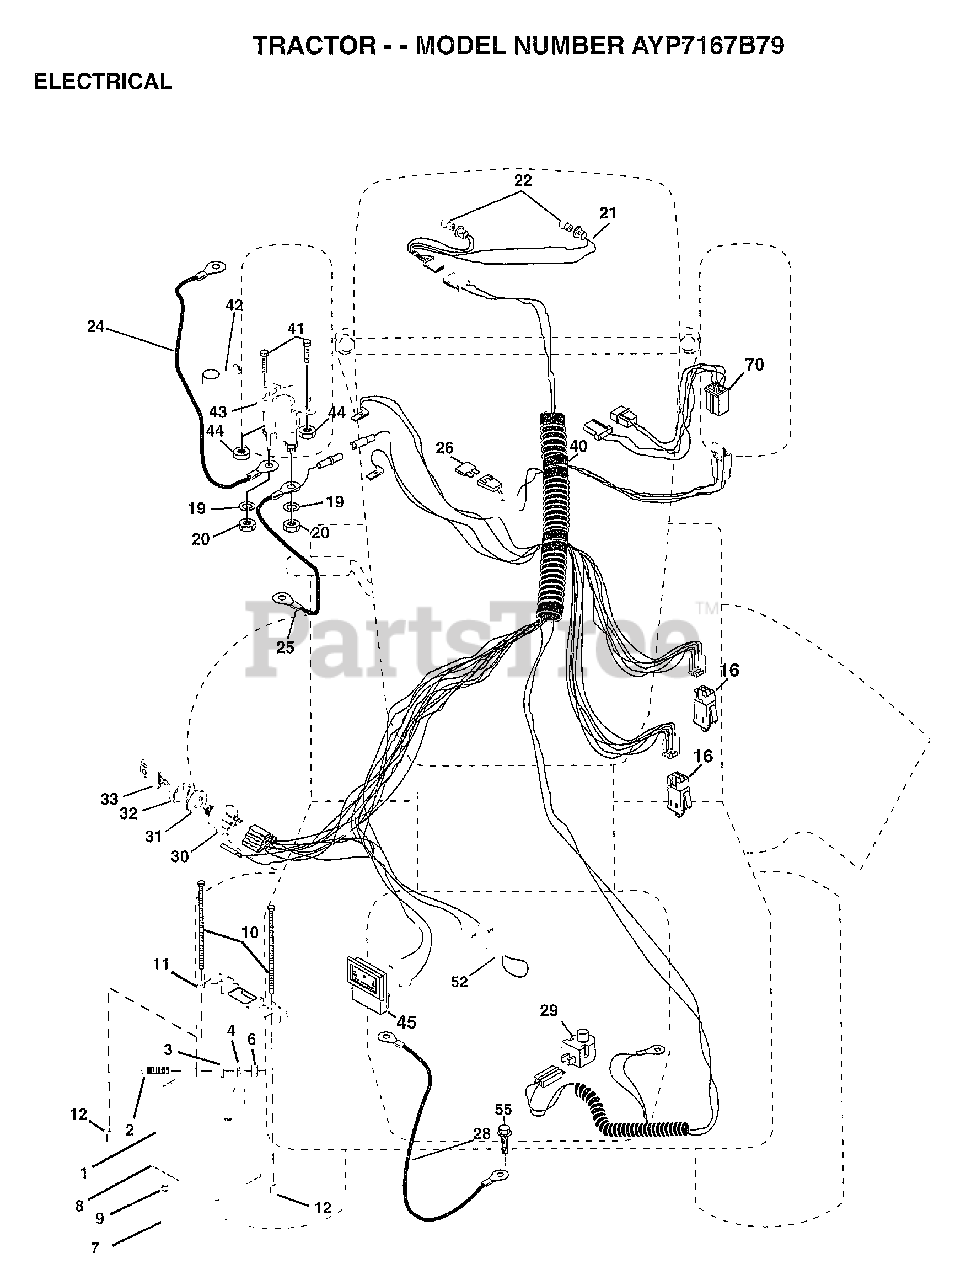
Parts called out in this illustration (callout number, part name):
2	BOLT LT
3	WASHER
4	LOCKWASHER
7	"DRAIN TU T, BATT"
8	"TRAY T, BATTERY"
9	HOSE CLAMP T
11	HOLDDOWN BATTERY
16	SWITCH INTERLOCK
20	NUT
21	"HARNESS,LIGHT SOC"
22	HEADLAMP BULB
24	"CABLE T, BATTERY"
25	CABLE.6GA.22W/16W
26	FUSE HYT
28	CABLE.GRND.6GA.21
29	SWITCH SEAT
30	SWITCH IGN 4POS
31	NUT IGNITION
32	COVER KEY SWITCH
33	KEY
40	HARNESS-IGNITION
41	BOLT HXHD FIN
44	NUT HXKEP 1/4X20
45	AMMETER
52	PROTECTION LOOP
55	SCREW LT
70	HARNESS.ENG.DUAL
